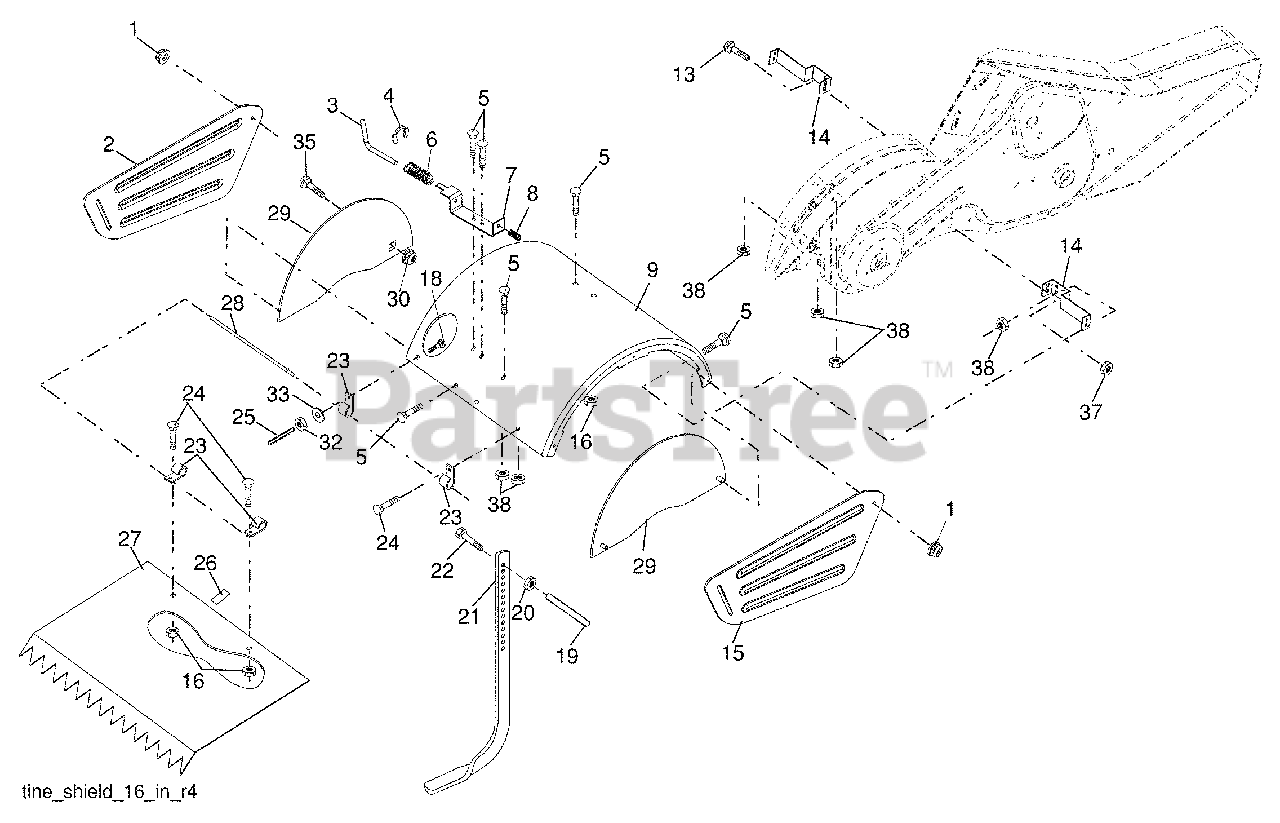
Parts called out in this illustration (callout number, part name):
1	Nut, Lock Hex Flange 5/16-18
2	Shield, Side, Outer L. H.
3	Pin, Stake, Depth
4	Ring, Klip
5	Bolt, Rdhd Sqnk 5/16-18 x 3/4
7	Bracket, Latch
8	Spring, Depth Stake
9	Shield, Tine
13	Bolt, Carriage 5/16-18 x 1-1/4
14	Bracket, Shield Tine
15	Shield, Side, Outer R.H.
16	Nut, Hex Flange 1/4-20 unc
18	Bolt, Carriage 1/4-20 x 1-1/4 Gr.
20	Nut, Hex 3/8-16
21	Stake, Depth
22	Bolt, Hex 3/8-16 x 2
24	Bolt, Carriage 1/4-20 x 1/2 Gr. 5
25	Cap, Vinyl
26	Pad, Idler
27	Shield, Leveling
28	Pin, Hinge
29	Shield, Side
30	Nut Lock Hex Flange
32	Nut Fin Hex 1/4-20 unc
33	Washer Lock Hvy Helical 1/4
35	Bolt, 5/16-18 x 5/8
37	Nut lock, 5/16-18 unc
38	Nut, Keps Hex 5/16-18 unc
